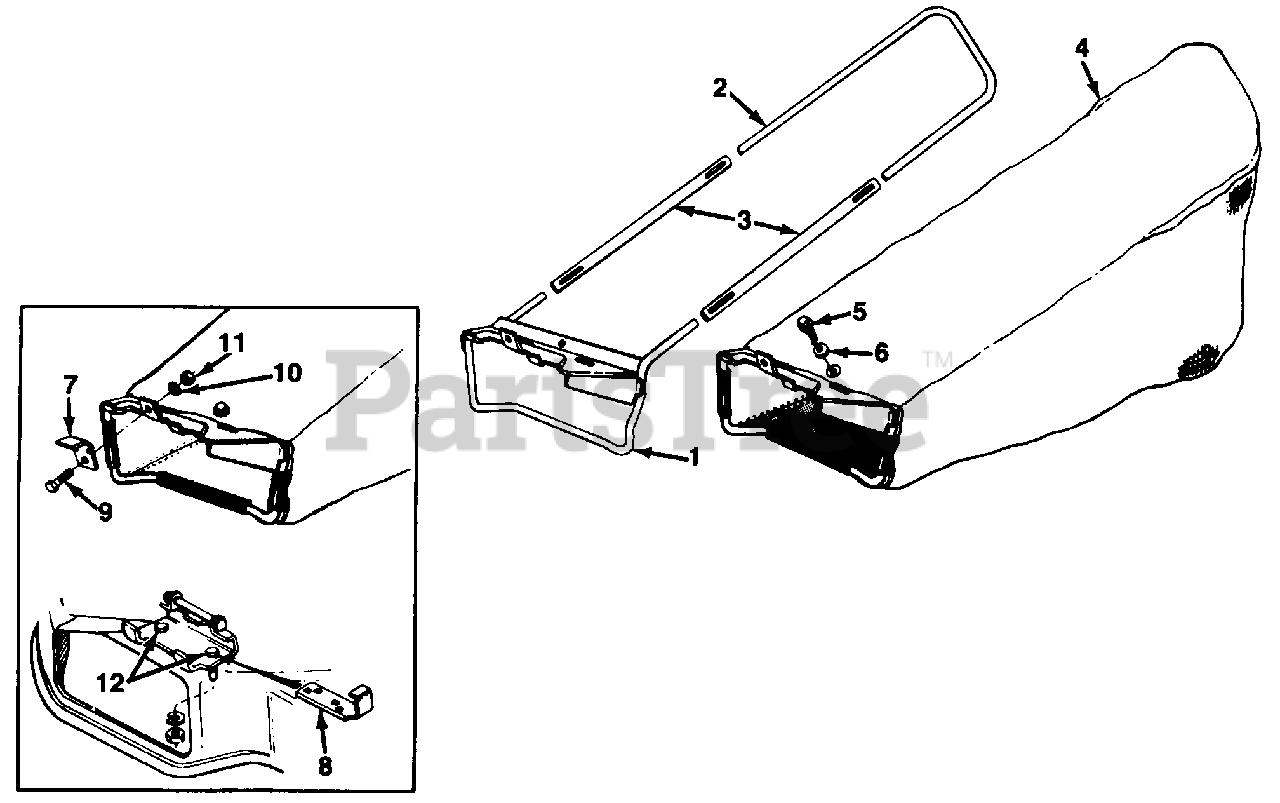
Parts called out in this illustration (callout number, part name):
4	Grass Bag
5	Hex Wash Hd. TT-Tap Scr. 1/4-20 x 5" Lg.
6	Bell-Wash. 1/4" I.D.
7	Deflector Stop
8	Support Plate
9	Hex Bolt 1/4-20 x .5" Lg.
10	L-Wash. 1/4" I.D.
11	Hex Nut 1/4-20 Thd.
12	Hex Bolt 1/4-20 x .62" Lg.
